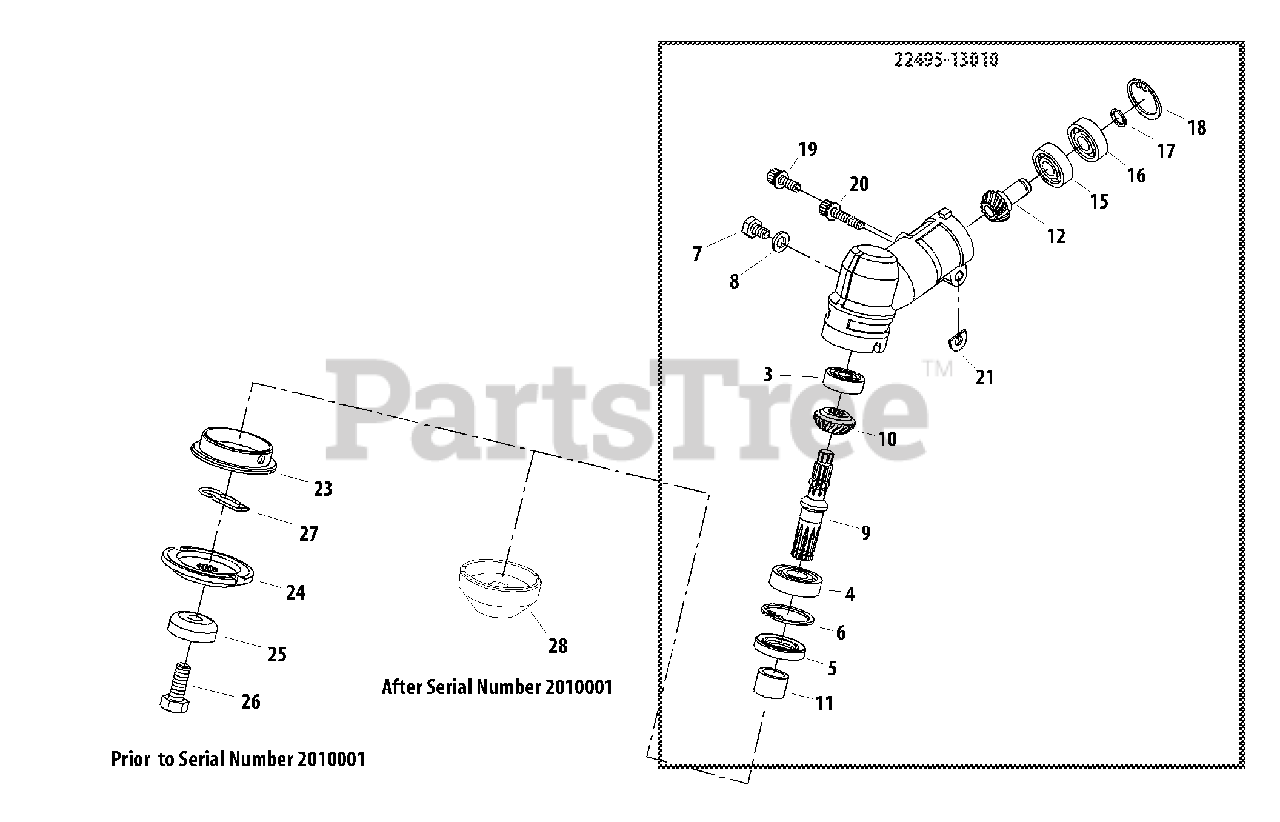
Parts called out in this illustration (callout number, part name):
3	BEARING, BALL 608 DDU
4	BEARING, BALL 6001
5	SEAL, OIL
6	RING, SNAP Ø28
7	BOLT M6×10
8	WASHER 6.5×11.5×0.8
9	SHAFT, GEAR
10	GEAR, BEVEL
11	SPACER
12	GEAR, PINION
15	BEARING, BALL 609
16	BEARING, BALL 609ZZ
17	RING, SNAP
18	RING, SNAP Ø24
19	BOLT M5×16
20	BOLT M5×25
21	D-WASHER
23	PLATE, ADAPTOR - UPPER
24	PLATE, ADAPTOR - LOWER
25	GUARD, BOLT
26	BOLT 8
27	CLIP, BLADE
28	HOLDER
22495-13010	GEAR CASE ASSY
